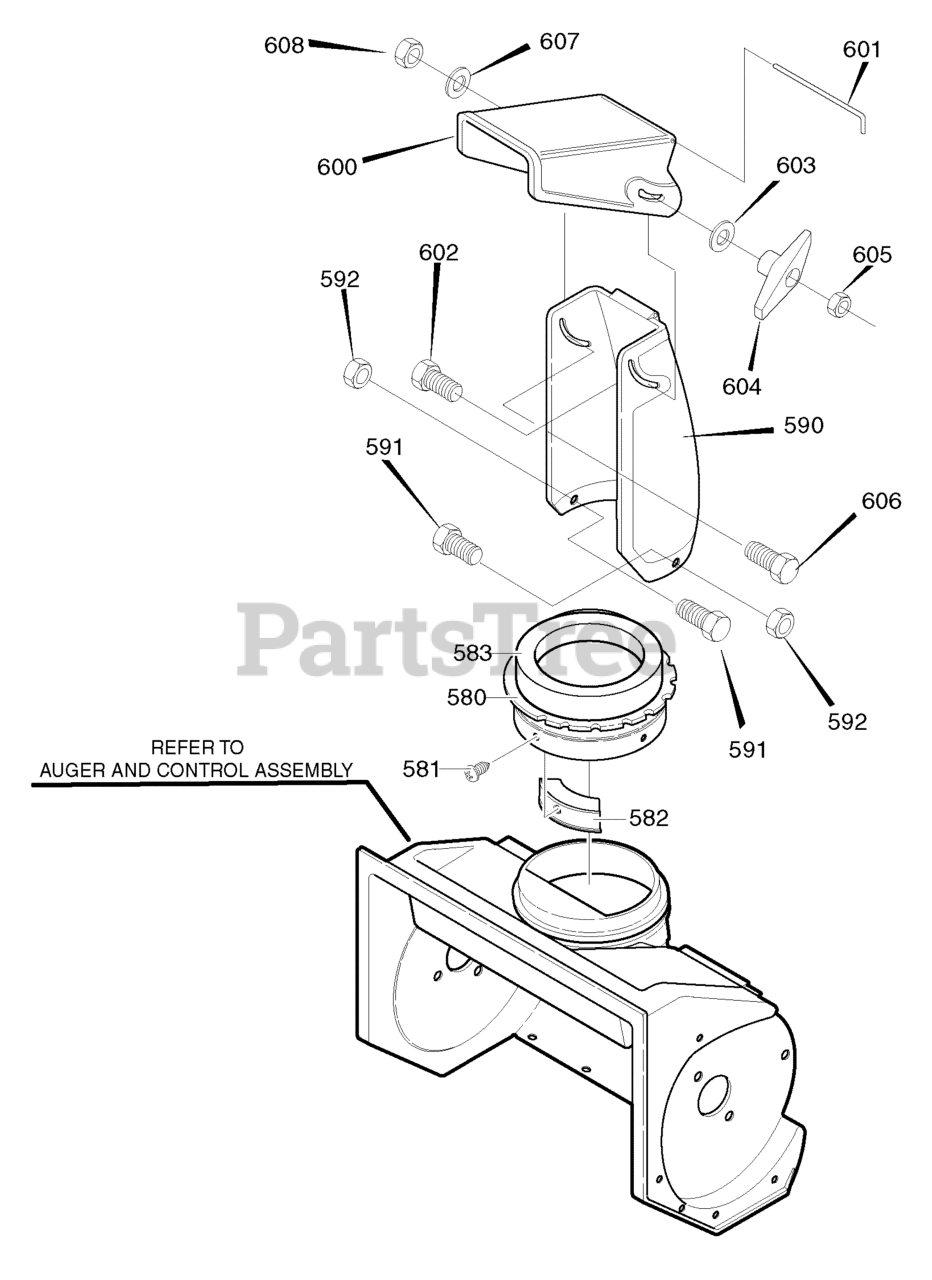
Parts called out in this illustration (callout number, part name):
580	RING, CHUTE
581	SCREW, #10 X .50
582	GUIDE, CHUTE
583	DONUT FOAM
590	CHUTE, DEFLECTOR LOWER
591	SCREW 1/4-20 X .50
592	NUT, 1/4-20
600	CHUTE DELFECTOR, UPPER
601	WIRE, CHUTE HINGE
602	BOLT, 5/16-18 X 1.25 CARRIAGE
603	WASHER, FLAT .349 X .69 X .066
604	KNOB, WING
605	NUT, 5/16-18
606	SCREW, 5/16-18 x 0.75
607	WASHER, FLAT .349 X .69 X .066
608	NUT, 5/16-18 HEX CONTROL LOCK
